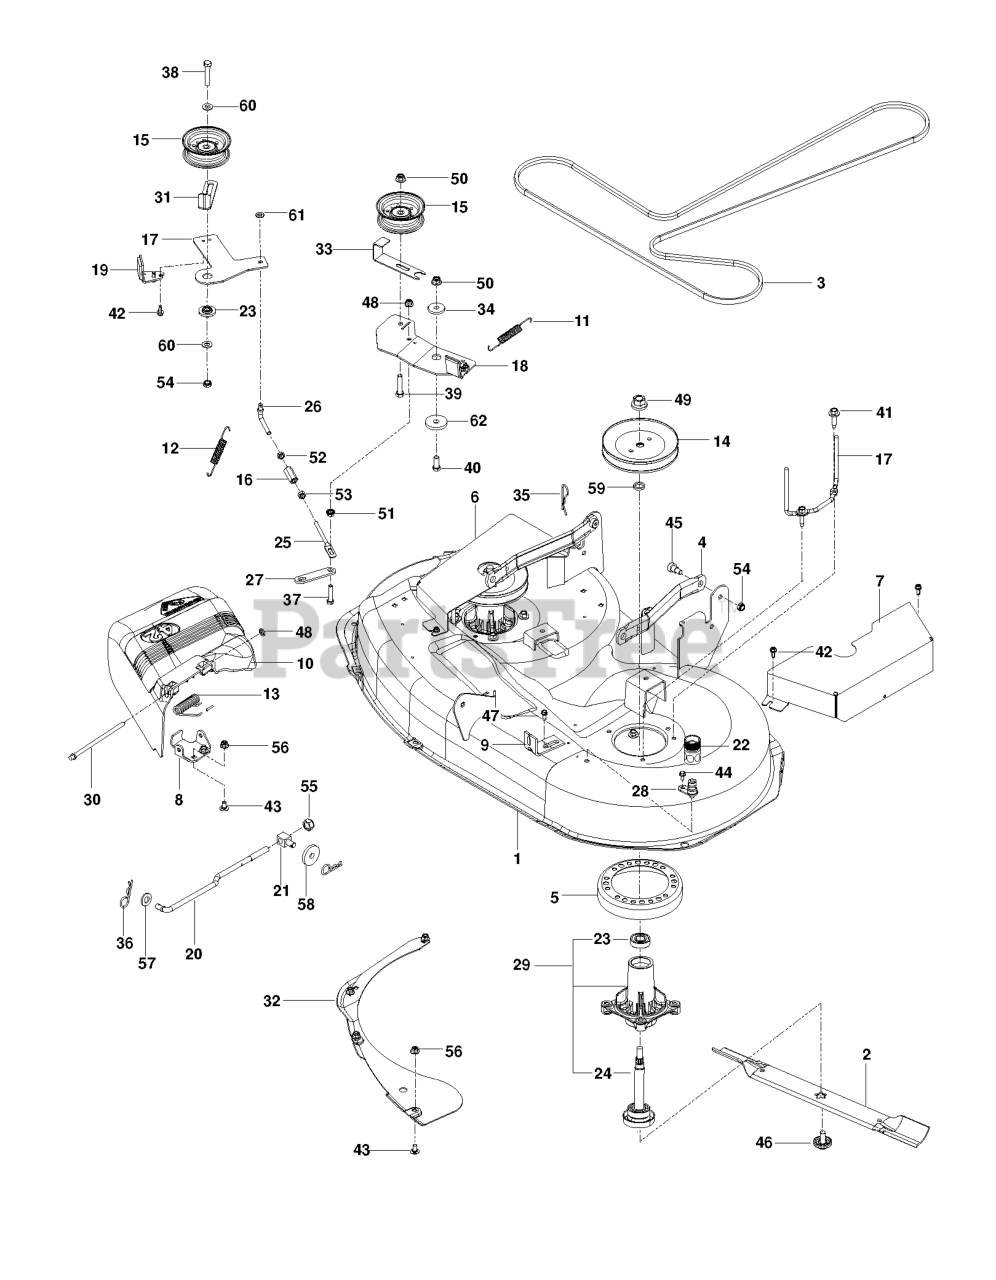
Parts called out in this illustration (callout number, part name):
1	DECK.SVC W/DECALS 42" HTC RZ
2	BLADE.42".MULCH
3	BELT, EL118
4	ARM.SUSPENSION.MOWER
5	STRIPPER-ROUND-UNIVERSAL
6	GUARD.RIGHT.BELT.42"BLACK
7	GUARD.LEFT.BELT.42" BLACK
8	BRKT.DEFLECTOR.38"2005+
9	BRACKET.CLUTCH.CABLE
10	DEFLECTOR 42
11	SPRING RETURN
12	SPRING BRAKE RETURN 42 SZ
13	SPRING, TORSION DEFLECTOR
14	PULLEY.MANDREL.5.438.P
15	IDLER PULLEY
16	PULLEY.IDLER.FLAT
17	ARM.BRAKE.42.BLACK
18	ARM.IDLER.BLACK
19	ARM, LH BRAKE
20	LINK LIFT SUSP. FRONT MOWER
22	COUPLING.QUICK CONNECT
24	SHAFT.ASM.MDRL.N/GREASE.38
26	LINK SZ42 ADJ, PINNED END
27	PLATE.ATTACHMENT.CLUTCH.(2 2)
28	PORT.WASHOUT
29	RB MANDREL.ASM.SUB-NON.GR
30	ROD, HINGE
31	GUIDE, BELT
32	BAFFLE VORTEX 42
33	KEEPER, BELT
34	SPACER.RETAINER
35	SPRING.RETAINER.YELLOW.ZINC
36	HAIRPIN #4
37	CAPSCREW 5/16 X 1/1/2 HEX HEAD
38	HCS 3/8C X 2
39	HCS 3/8-16 X 1 3/4 GR5
40	HCS 3/8-16X1.GRD.5.ZD
41	WASHER HEAD SCREW
42	SCREW- 1/4-20 X 5/8
43	CARRIAGE BOLT 5/16C X 5/8"
44	SCREW 3/8C X 3/4 HEX CAP
45	SB 3/8-16 X 3/8 SKT HD ZD
46	BOLT.WASHER.ASM.7/16-2
47	BOLT.5/16HEX.WHS.HD
48	NUT PUSH M
49	LOCKNUT - 9/16
50	NUT 3/8-16 HEX FLG NYLOC ZD
51	NUT 5/16C WHIZ
52	NUT 5/16F LEFTHAND
54	NUT HEX 3/8-16 NYLON, THIN
55	NUT, 7/16-20 HEX NYLOC ZC
56	5/16-18 NYLOC FLANGE NUT
57	WASHER STEEL
58	SPINDLE WASHER
59	WASHER.SPACER.MANDREL
60	WASHER
61	WASHER
62	WASHER, FRICTION
